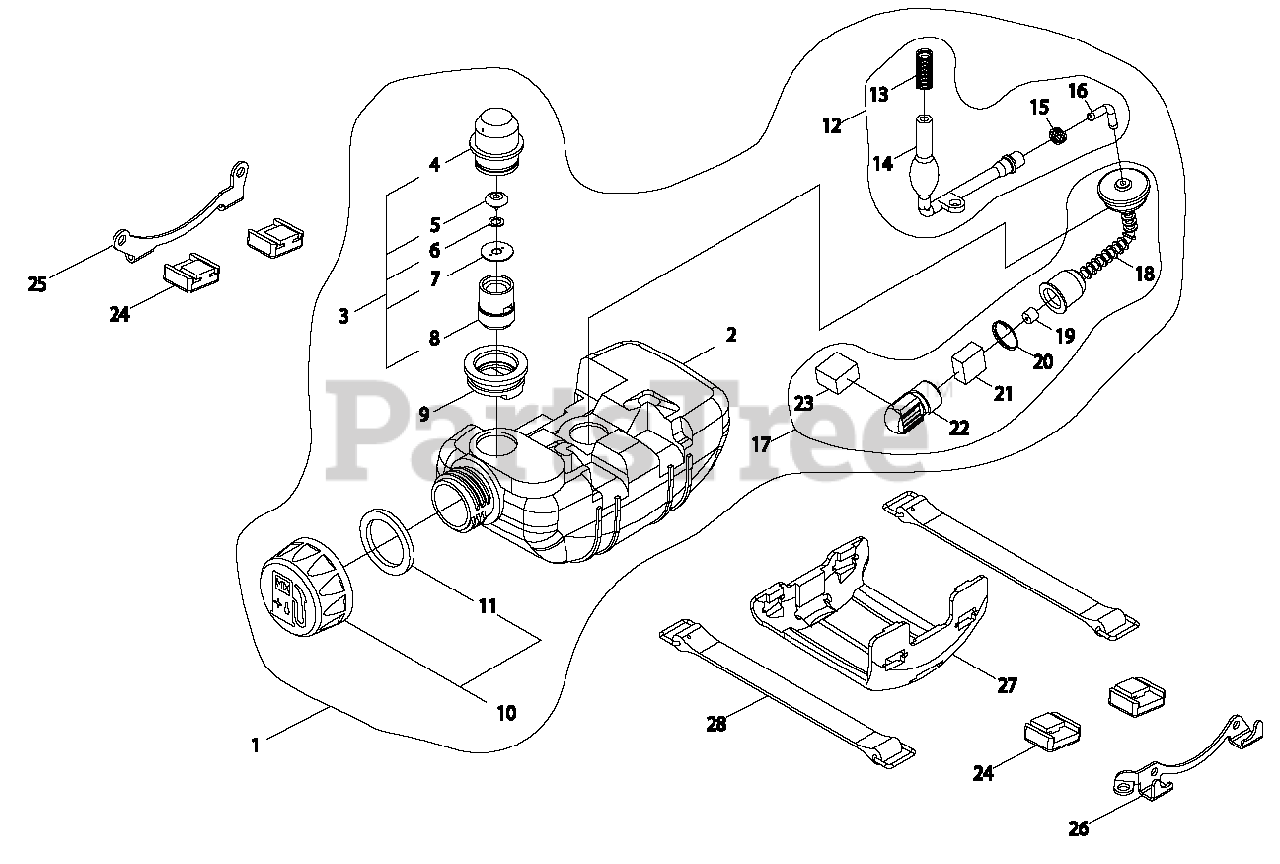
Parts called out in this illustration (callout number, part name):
1	FUEL TANK ASSY
2	TANK, FUEL
3	VENT ASSY
4	CAP, BREATHER
5	VENT, FUEL TANK
6	WASHER
7	RETAINER
8	HOLDER, VENT
9	GROMMET
10	CAP ASSY
11	GASKET, CAP
12	FUEL PIPE ASSY
13	CLAMP
14	PIPE - FUEL
15	CLIP - 7.8
16	CONNECTOR, PIPE
17	FUEL FILTER ASSY
18	PIPE - FUEL
19	VALVE, CHECK
20	CLIP
21	FILTER, FUEL - B
22	WEIGHT, FUEL FILTER
23	FILTER, FUEL - A
24	CUSHION
25	BRACKET - INNER
26	BRACKET - OUTER
27	GUARD, FUEL TANK
28	STRAP, FUEL TANK
